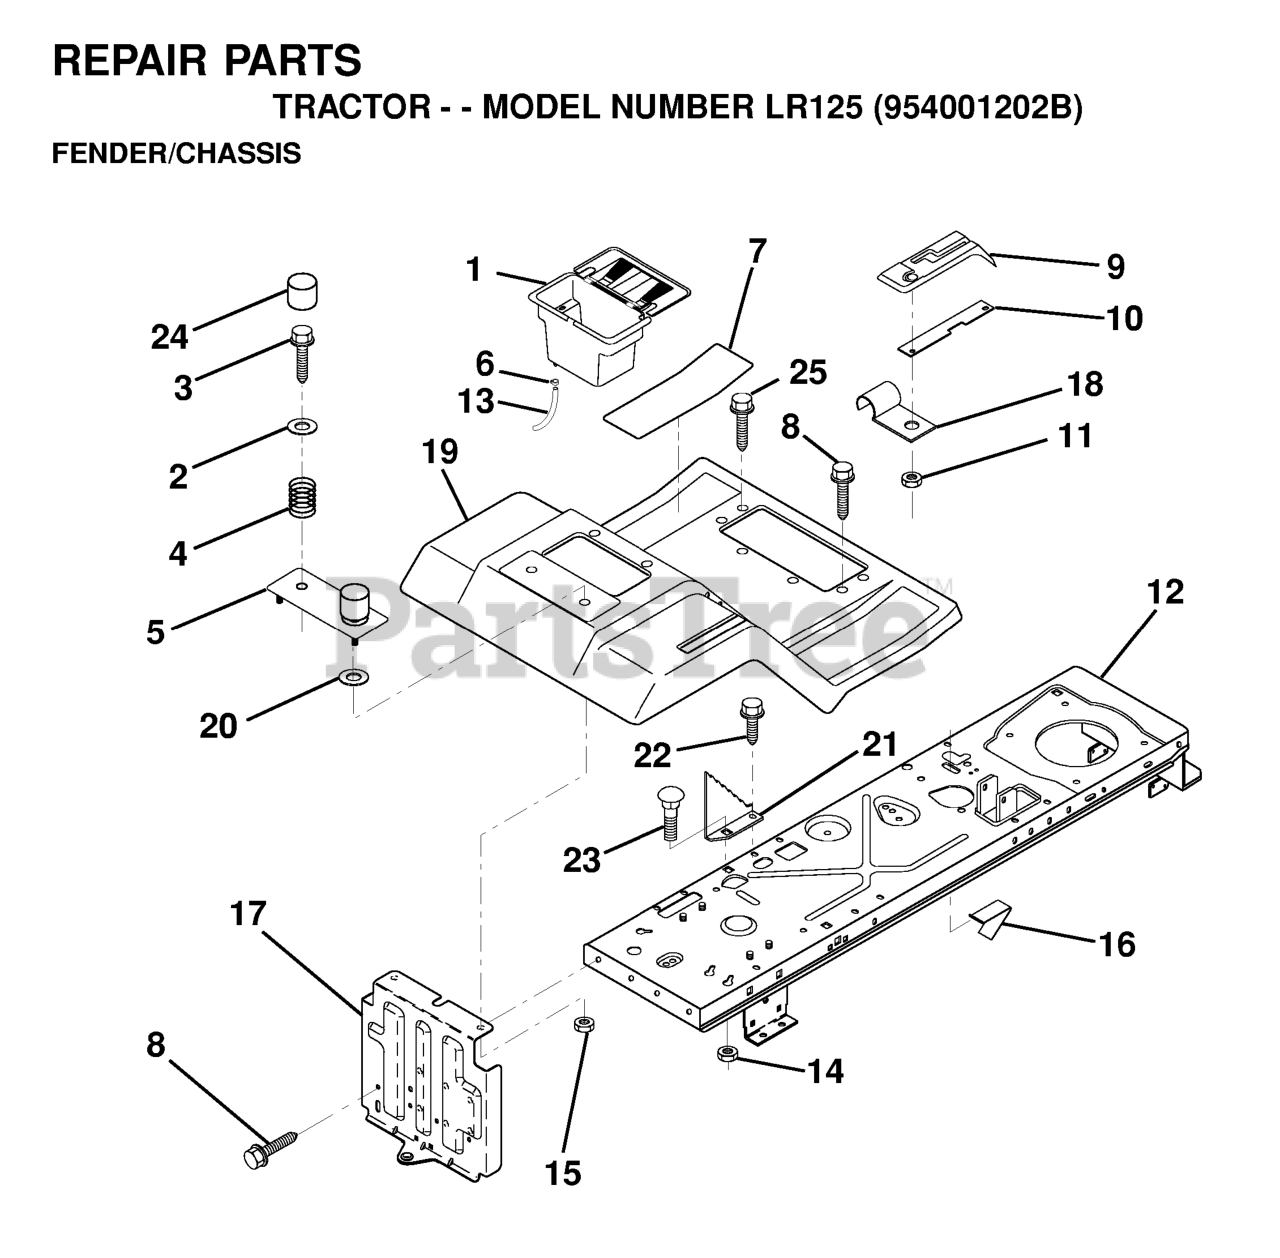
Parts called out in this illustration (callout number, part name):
1	BATTERY CASE
2	WASHER
3	SCREW
4	SPRING COMPRESSION
5	PLATE ASM BATTERY
6	HOSE CLAMP T
7	FOOTREST PAD
8	SCREW.THDROL.5/16-18X3/4.TTY
9	CONSOLE,SHT CONTR
10	BAR, SHIFT LOCK
11	NUT.PUSH.3/16
13	TUBE BATTERY DRAIN
14	LOCKNUT
15	Nut, Keps Blk Hex 1/4-20 UNC
16	SWITCH ACTUATOR
18	CLIP,INSULATOR
19	FENDER FRONT ASSY
20	WASHER
21	BRACKET DEPTH
22	Screw 5/16-18 x 1/2 Hex, Self Tapping 5/16-18 x 1/2
23	BOLT.CARR.SQNK.5/16-18UNC.X3/4
24	CAP SPRING
25	Screw Hex Wsh Thdroll 5/16-18 x 1
